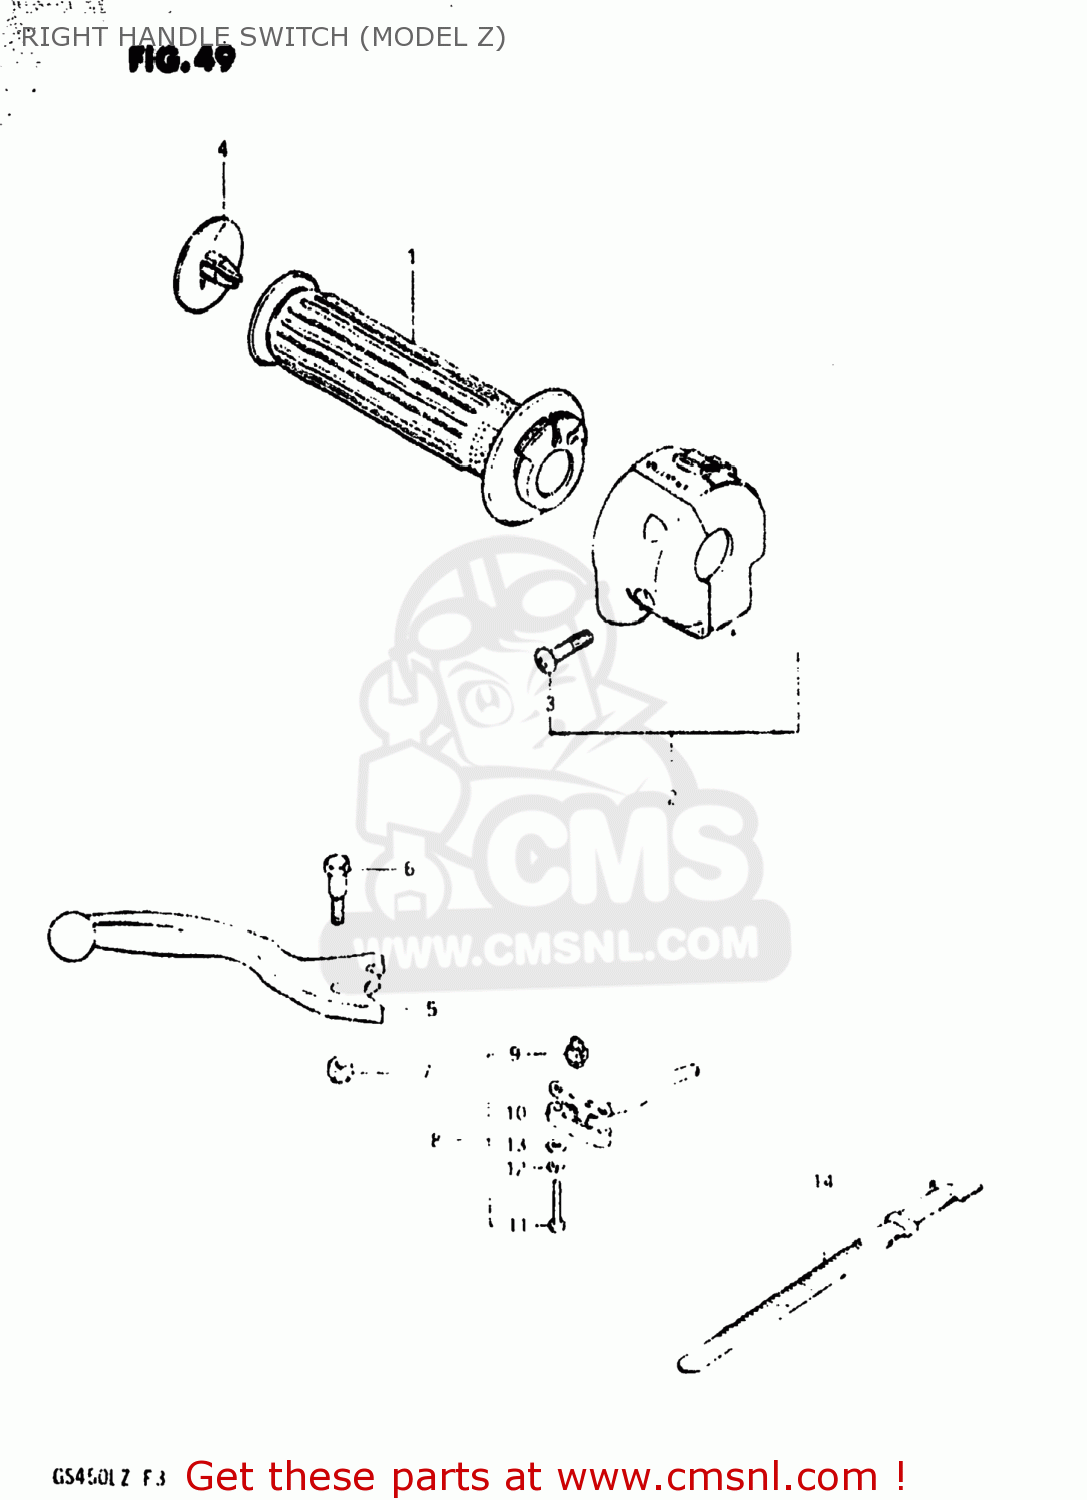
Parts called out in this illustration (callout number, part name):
1	GRIP,THROTTLE
2	SWITCH ASSEMBLY,HANDLE,RIGHT
3	SCREW
4	CAP,GRIP END
5	LEVER,BRAKE
6	BOLT
7	NUT 6MM
8	SWITCH ASSEMBLY
9	CONTACT,SWITCH
10	COVER,FR BK TERMINAL BASE
11	SCREW
12	LOCK WASHER
13	WASHER
14	CLAMP(L:120)
